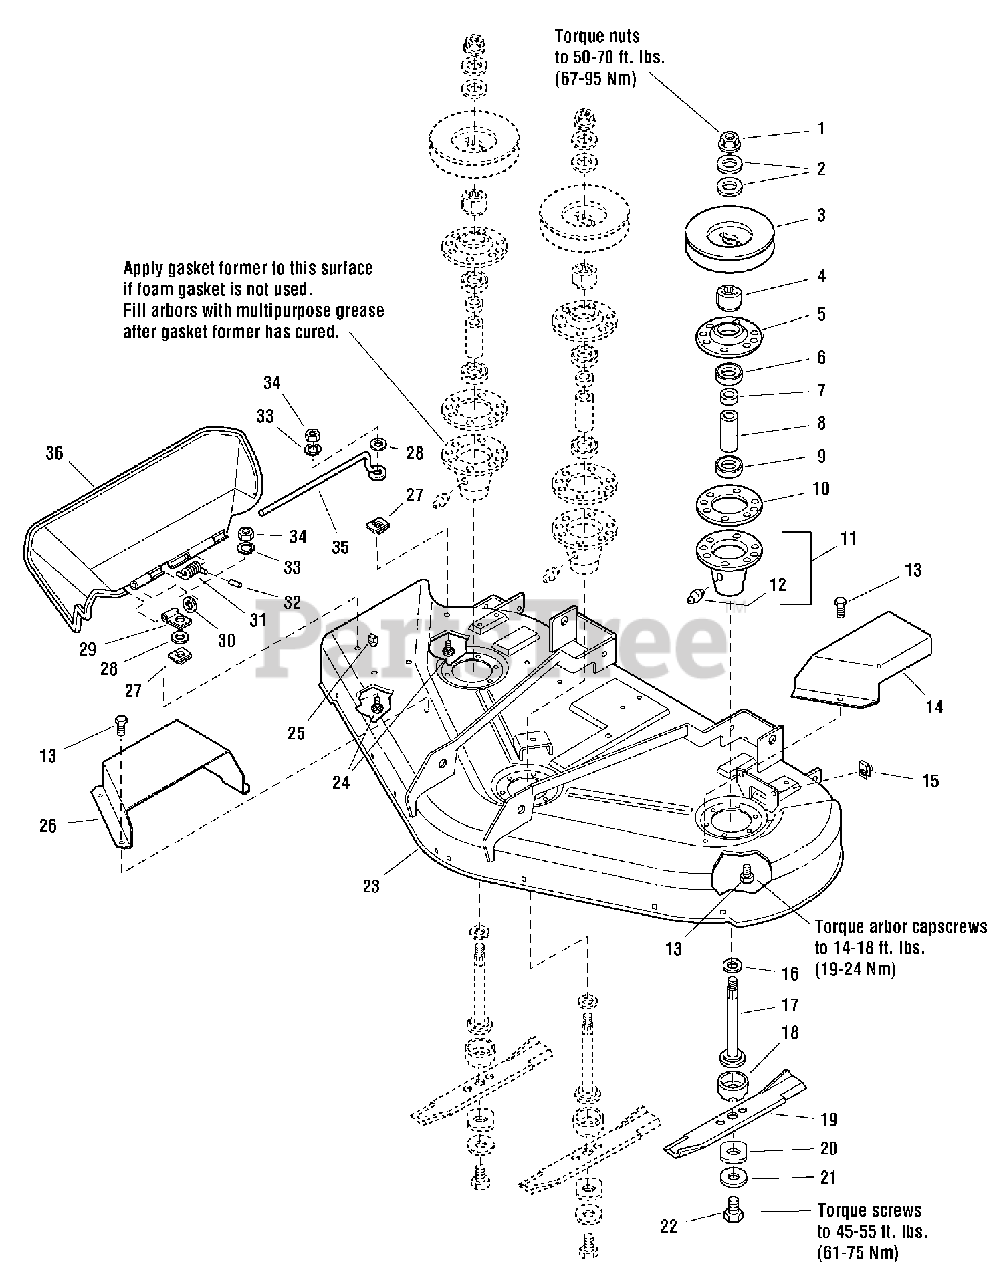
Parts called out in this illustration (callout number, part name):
1	NUT, Hex Flange, 9/16-18
2	WASHER, Bellevilled, 9/16
5	COVER, Arbor Housing
6	BEARING, Ball, 3/4 X 1-3/4 X 5/8
7	SPACER, 21/32 X 3/4 X 5/8
8	SPACER, 11/16 X 5/32 X 2-11/16
9	BEARING, Ball, 11/16 X 1-9/16 X 15/32
11	HOUSING ASSEMBLY, Arbor Bottom, w/Lube Fitting
12	FITTING, Grease
13	CAPSCREW, Hex Head Taptite, 5/16-18 X 3/4
14	COVER, Arbor, LH, Orange
14	COVER, Arbor, LH, Red
15	BODY CLIP, 5/16-18
16	WASHER, 9/16, BLACK
17	SHAFT, Arbor, 6-1/2
18	SHIELD, Grass, Lower
19	BLADE, Mower, 16-1/8
19	BLADE, Mower, 18-1/8 (FOR 50" DECKS)
20	WASHER, Hex, 11/16 X 2
21	WASHER, Spring, 15/32, BLACK
22	CAPSCREW, Hex Head, 7/16-14 X 1-1/4
23	MOWER HOUSING ASSEMBLY, 44" Mower, Orange (Includes Decals)
23	MOWER HOUSING ASSEMBLY, 50" Mower, Orange (Includes Decals)
23	MOWER HOUSING ASSEMBLY, 44" Mower, Red (Includes Decals)
23	MOWER HOUSING ASSEMBLY, 50" Mower, Red (Includes Decals)
24	CARRIAGE BOLT, 1/4-20 X 7/8
26	COVER, Arbor, RH, Orange
26	COVER, Arbor, RH, Red
27	NUT, Push
28	WASHER, 1/4, BLACK
30	WASHER, 5/16, BLACK
31	SPRING, Torsion, Chute
33	LOCKWASHER, 1/4
34	NUT, Hex, 1/4-20
35	ROD, Deflector
36	DEFLECTOR, Plastic
